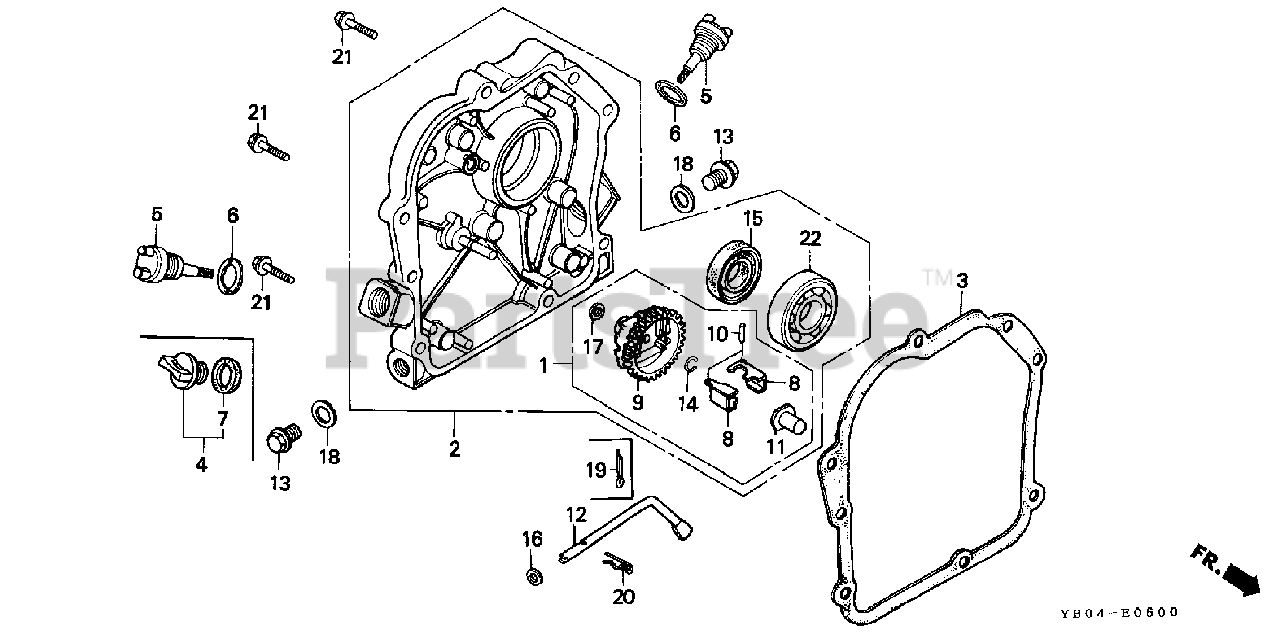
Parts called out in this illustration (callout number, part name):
2	COVER ASSY., CRANKCASE
3	GASKET, CASE COVER
5	CAP, OIL FILLER (NOT AVAILABLE)
6	GASKET, OIL FILLER CAP
8	WEIGHT, GOVERNOR
9	HOLDER, GOVERNOR WEIGHT
9	HOLDER, GOVERNOR WEIGHT (NOT AVAILABLE)
11	SLIDER, GOVERNOR
12	SHAFT, GOVERNOR ARM
13	BOLT, DRAIN PLUG
14	CLIP, GOVERNOR HOLDER
15	OIL SEAL (17X30X6) (NOK)
16	WASHER, PLAIN (5MM)
17	WASHER, PLAIN (6MM)
18	WASHER, DRAIN PLUG (12MM)
19	PIN, GOVERNOR WEIGHT
19	PIN, COTTER (2.5X28)
20	PIN, LOCK (8MM)
21	BOLT, FLANGE (6X28)
22	BEARING, RADIAL BALL (6203)
